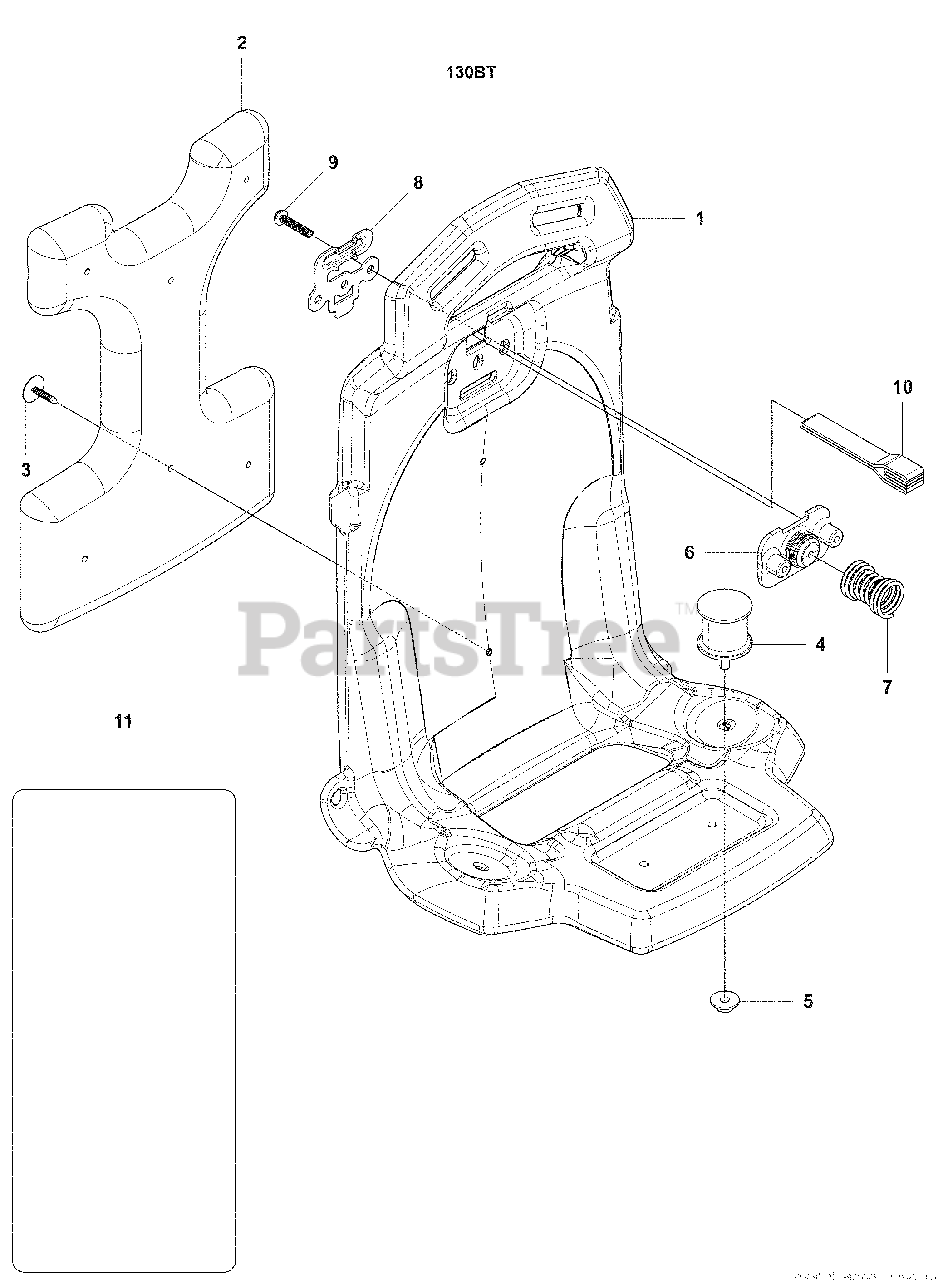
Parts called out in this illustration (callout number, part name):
3	Clip
4	Damper
5	Nut
9	Screw
11	Caution Label
